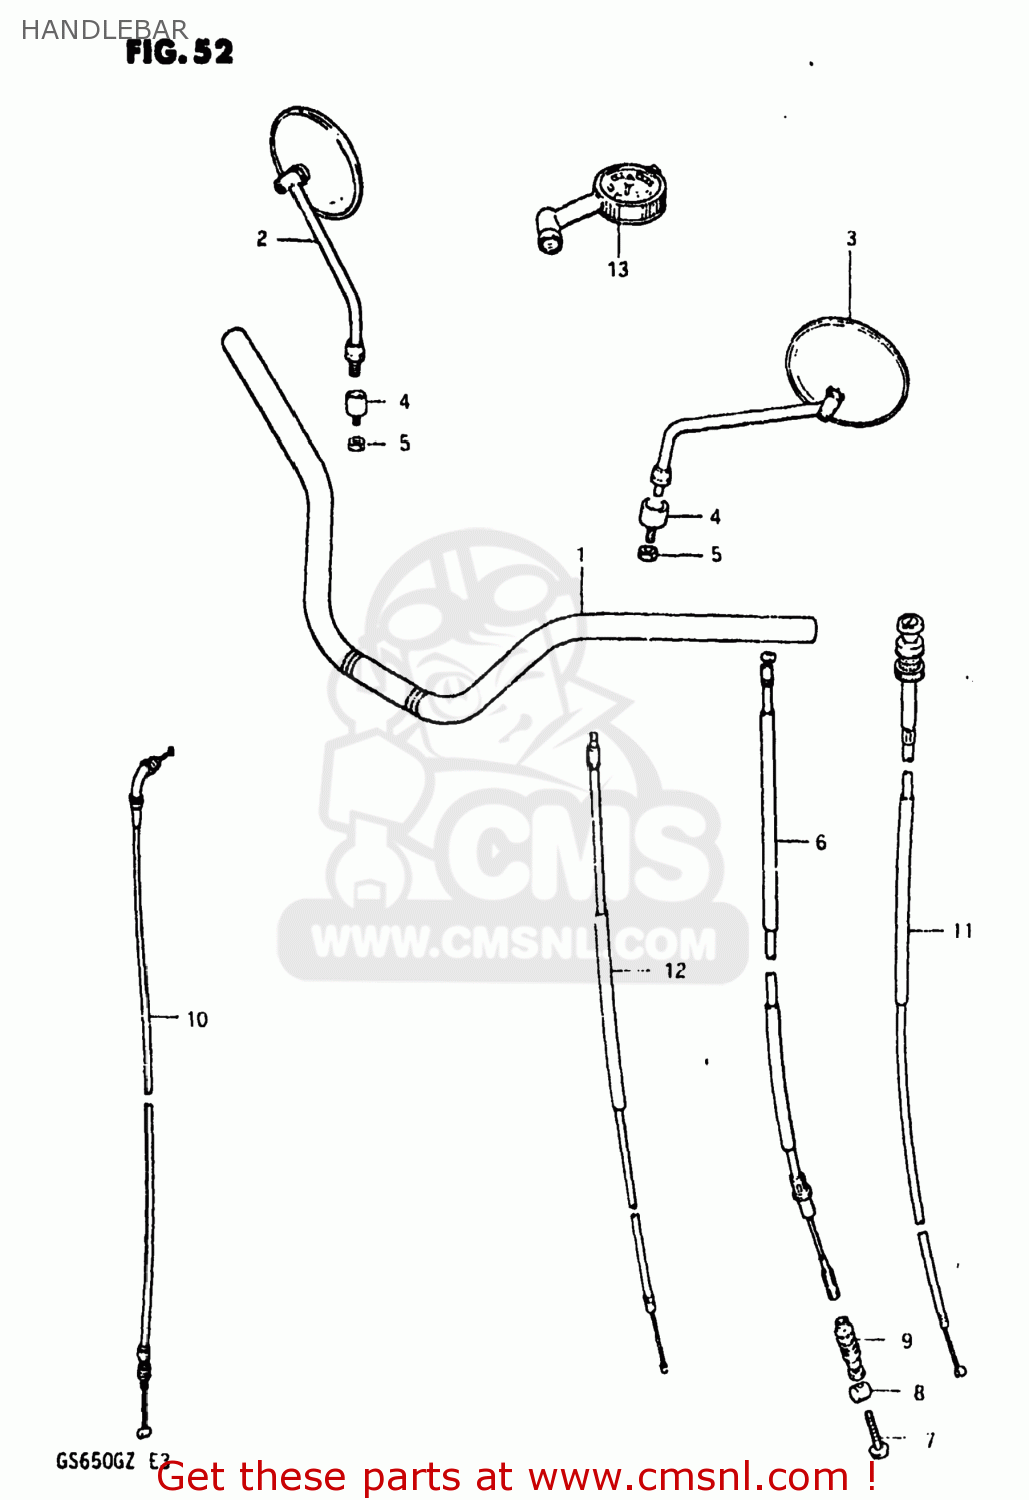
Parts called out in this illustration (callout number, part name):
1	HANDLEBAR
2	MIRROR ASSEMBLY,RIGHT
3	MIRROR ASSEMBLY,LEFT
4	CUSHION,REAR VIEW MIRROR
5	NUT
6	CABLE ASSEMBLY,CLUTCH
7	SCREW
8	PIN
9	DUST SEAL
10	CABLE ASSEMBLY,THROTTLE
11	CABLE ASSEMBLY,STARTER
12	CABLE COMP,STARTER
13	GAUGE ASSY,AIR PRESSURE
